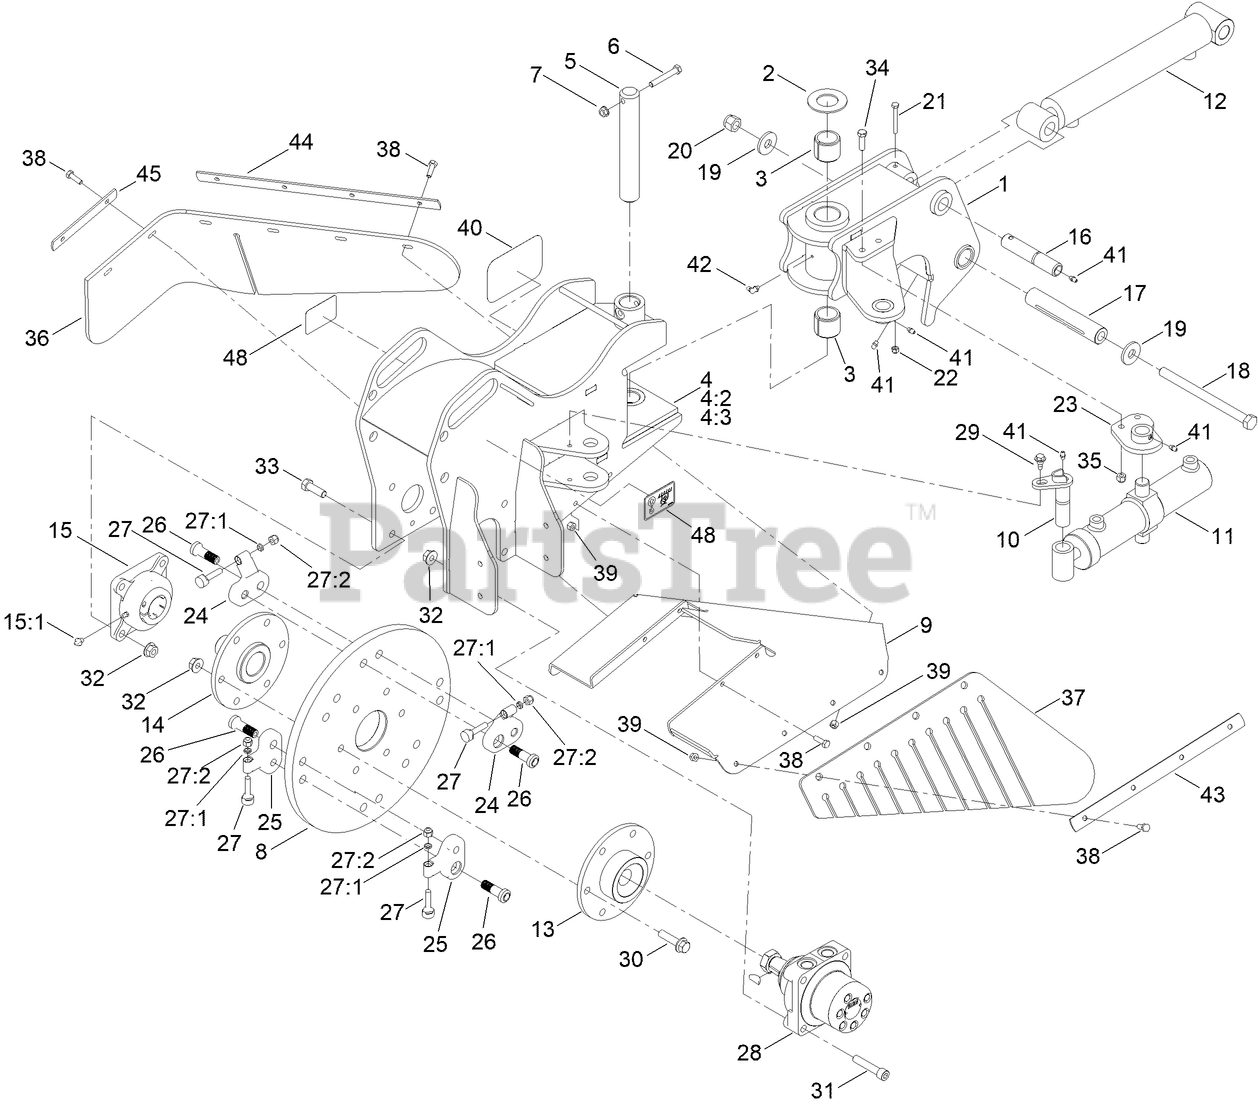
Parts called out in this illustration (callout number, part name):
2	WASHER
3	BUSHING-TENSION
4	FRAME ASM
4:2	DECAL-WARNING
4:3	DECAL-DANGER
5	PIN-PIVOT
6	SCREW-HH
7	NUT-HHF, WHIZ
8	WHEEL-CUTTER
9	SHIELD-GRINDER
10	PIN-PIVOT
11	HYD CYLINDER ASM
12	HYD CYLINDER ASM
13	HUB-DRIVE
14	SHAFT-STUB
15	BEARING
15:1	FITTING-GREASE
16	PIN-PIVOT
17	SPACER-PIVOT
18	BOLT-HH
19	WASHER-HARDENED
20	NUT-LOCK, NI
21	SCREW-HH
22	NUT-LOCK, NI
23	MOUNT-CYLINDER
24	POCKET-ANGLED
25	POCKET-STRAIGHT
26	BOLT-HSH, RH
27	GRINDER TOOTH ASM
27:1	NUT-LOCK, NI
27:2	SPACER-TOOTH
28	HYD MOTOR ASM
29	BOLT-SHOULDER
30	SCREW-HHF
31	SCREW-HSH
32	NUT-HHF
33	SCREW-HH
34	SCREW-HH
35	NUT-LOCK, NI
36	SHIELD-RUBBER, RH
37	SHIELD-RUBBER, LH
38	SCREW-HH
39	NUT-LOCK, NI
41	FITTING-GREASE
42	FITTING-GREASE, 90 DEG
43	STRAP-RETAINER,LH
44	STRAP-RETAINER,REAR
45	STRAP-RETAINER,RH
48	DECAL-LIFT/TIE DOWN
